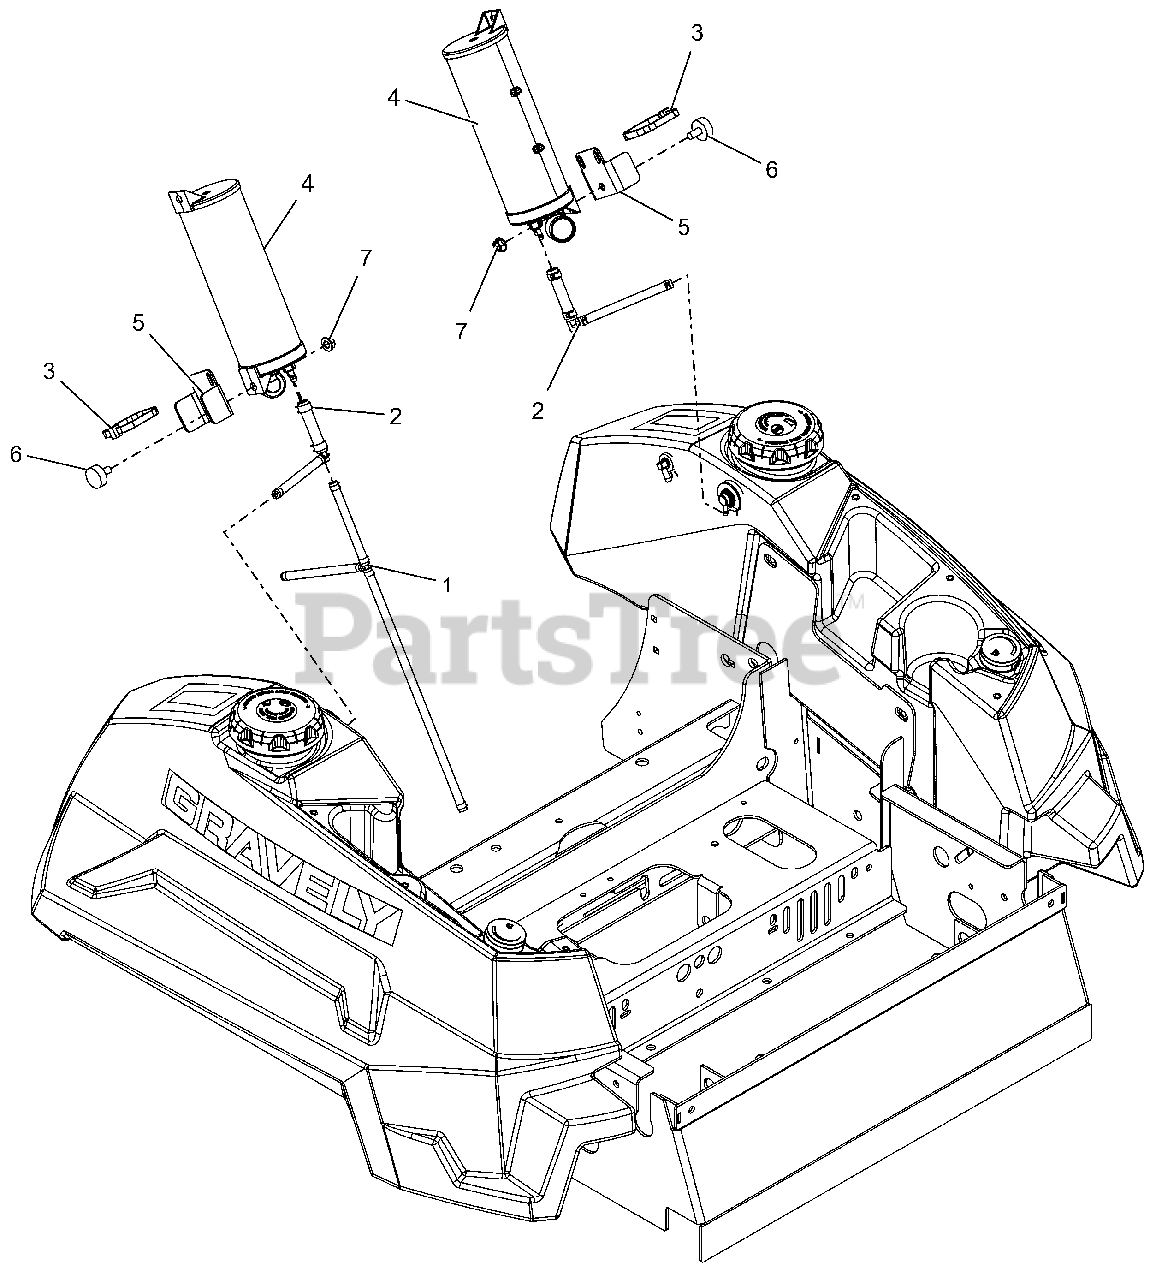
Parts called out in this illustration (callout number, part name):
1	ASM, YAMAHA VAPOR LINE (CARB)
2	ASM, CANISTER VENT LINE
3	TIE WRAP, 15.25" X 120 LBS
4	CANISTER, CARBON 9.3G CAP.
5	CARB CANISTER MTG BRKT - BLACK
6	BUMPER, RUBBER
7	@NUT-SPNLK-FLG .312-18 YWZC
